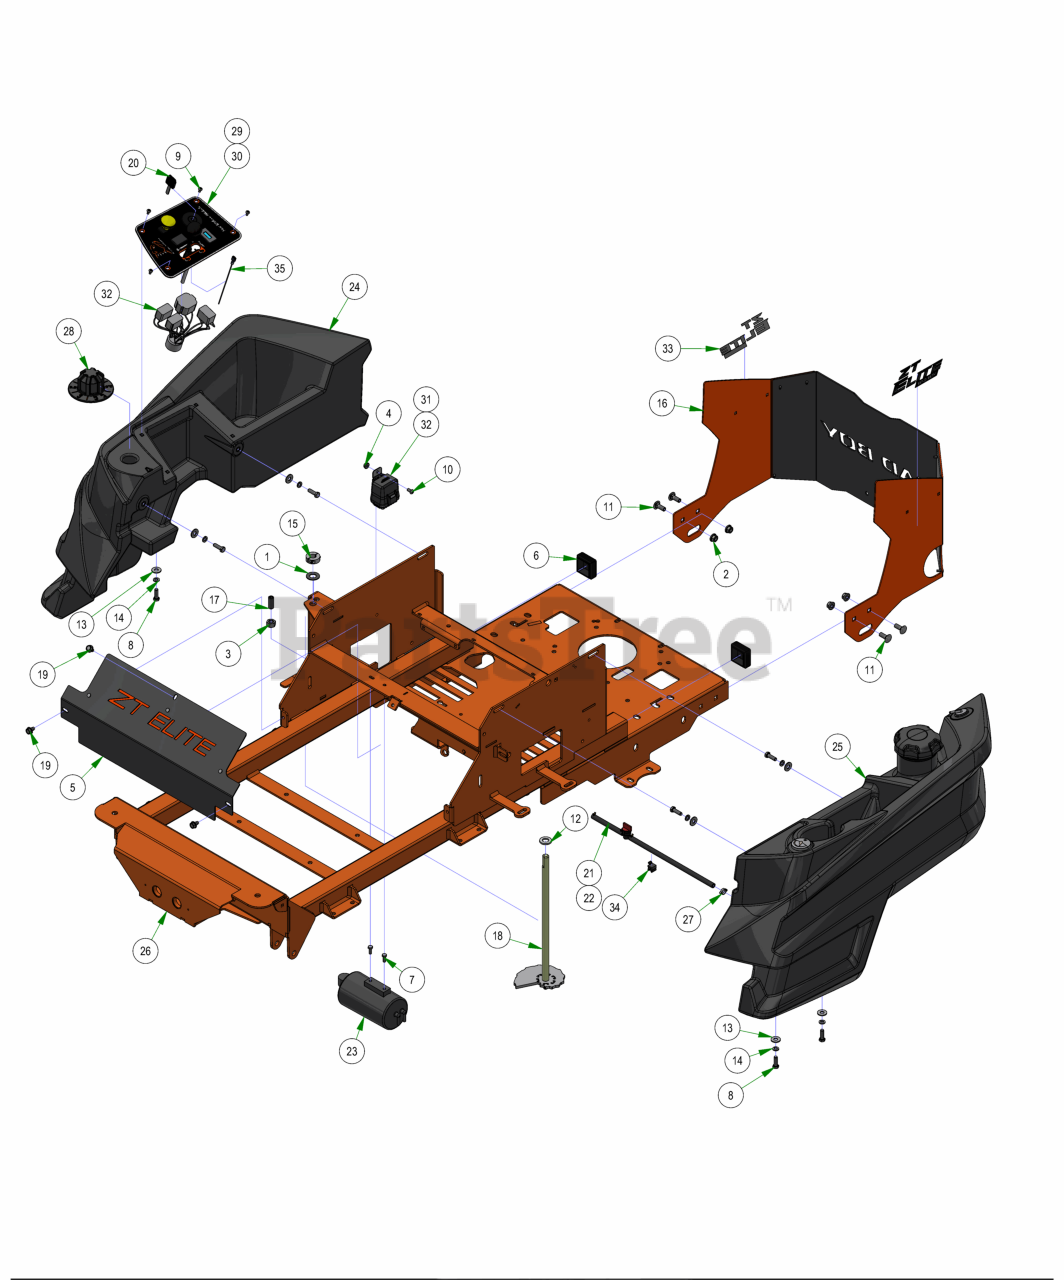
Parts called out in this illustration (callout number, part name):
1	.625 ID x 1.250 OD x .062 THK F/W Nylon
2	3/8-16 NYLON INSERT FLANGE LOCKNUT (GR.F) ZINC
3	1/2-13 HEX NUT ZINC
4	1/4-20 HEX SERRATED FLANGE NUT HARD/ZINC
5	2023 ZT Elite Cooler Cover Assembly
6	2X2 Frame Plug
7	M6-1.0 X 16MM DIN 933 HEX TAP BOLT (CL 8.8) ZINC
8	5/16-18 X 1 HEX CAP SCREW (GR.5) ZINC
9	10-32 X 3/8 BUTTON SOCKET CAP SCREW 18-8 STAINLESS STEEL
10	1/4-20 X 1/2 BUTTON SOCKET CAP SCREW 18-8 STAINLESS STEEL
11	3/8-16 X 1 CARRIAGE BOLT (GR.5) ZINC
12	.635 ID X 1.120 OD X .140 THICK FLAT WASHER NYLON
13	5/16 USS FLAT WASHER (7/8 OD) ZINC
14	5/16 SPLIT LOCKWASHER ZINC
15	5/8" Split Collar
16	2022 ZT Elite Rear Cover Assembly
17	Dial Rod Plunger
18	ZT Deck Height Bar Assembly
19	5/16-18 X 1/2 HWH unslot (F) tcs zinc
20	Ignition Key
21	15" Fuel Line Assembly
22	37" Fuel Line Assembly
23	ZT/Mav EPA Cannister Assy
24	2021 Maverick Right Side Tank
25	2021 Maverick Left Side Tank
26	2025 ZT Elite Frame
27	2 EAR CLAMP 12.5mm-15mm
28	MZ/ZT Deck Height Dial
29	2023 Control Panel Assembly
30	2025 ZT/MAV/HD Control Panel Assembly
31	2024 Wiring Harness with Clips
32	2025 Wiring Harness with Clips and Lights
33	ZT Elite Back Plate Decal
34	Edge Clip With Ziptie
35	2017 MZ/ZT/MAV Tach Wire Assy
